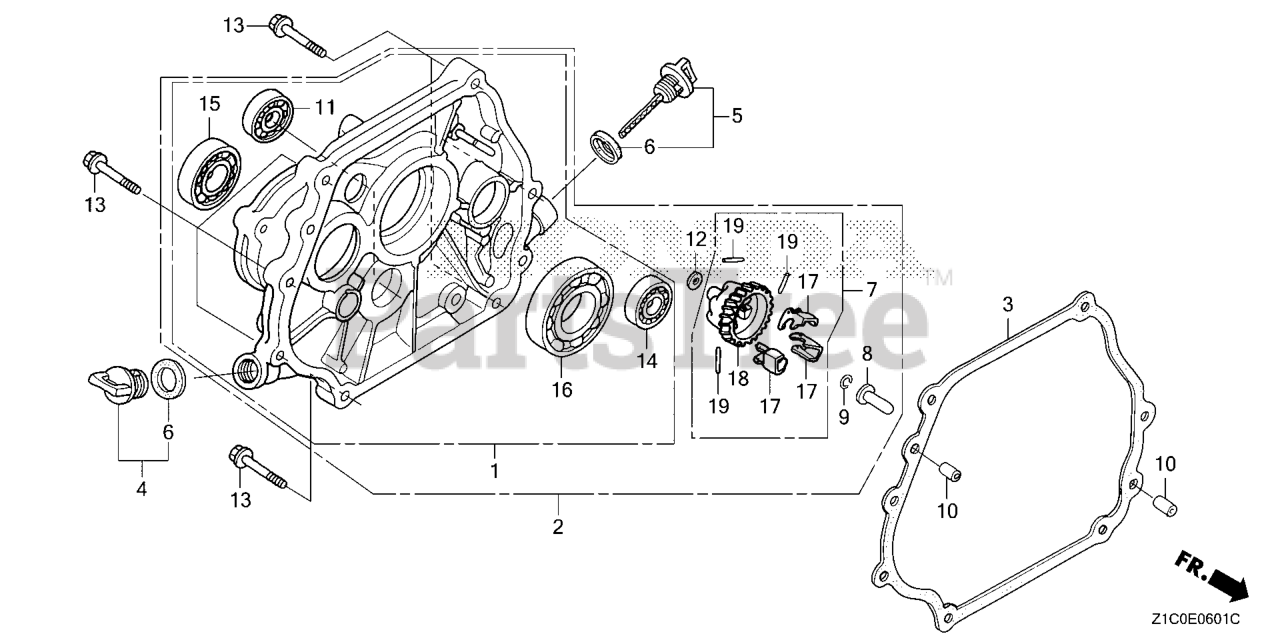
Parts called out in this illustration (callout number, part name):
2	COVER ASSY., CRANKCASE
3	GASKET, CRANKCASE COVER
4	CAP ASSY., OIL FILLER
5	CAP ASSY., OIL FILLER
6	GASKET, OIL FILLER CAP
7	GOVERNOR ASSY.
8	SLIDER, GOVERNOR
9	CLIP, GOVERNOR HOLDER
10	PIN, DOWEL (8X12)
11	BEARING, RADIAL BALL (6202)
12	WASHER, PLAIN (6MM)
13	BOLT, FLANGE (8X40) Use up to Engine SN 1003236.
14	BEARING, RADIAL BALL (6202) (FUJIKOSHI)
14	BEARING, RADIAL BALL (6202)
15	BEARING, RADIAL BALL (6204)
16	BEARING, RADIAL BALL (6207)
17	WEIGHT, GOVERNOR
18	HOLDER, GOVERNOR WEIGHT
19	PIN, GOVERNOR WEIGHT
